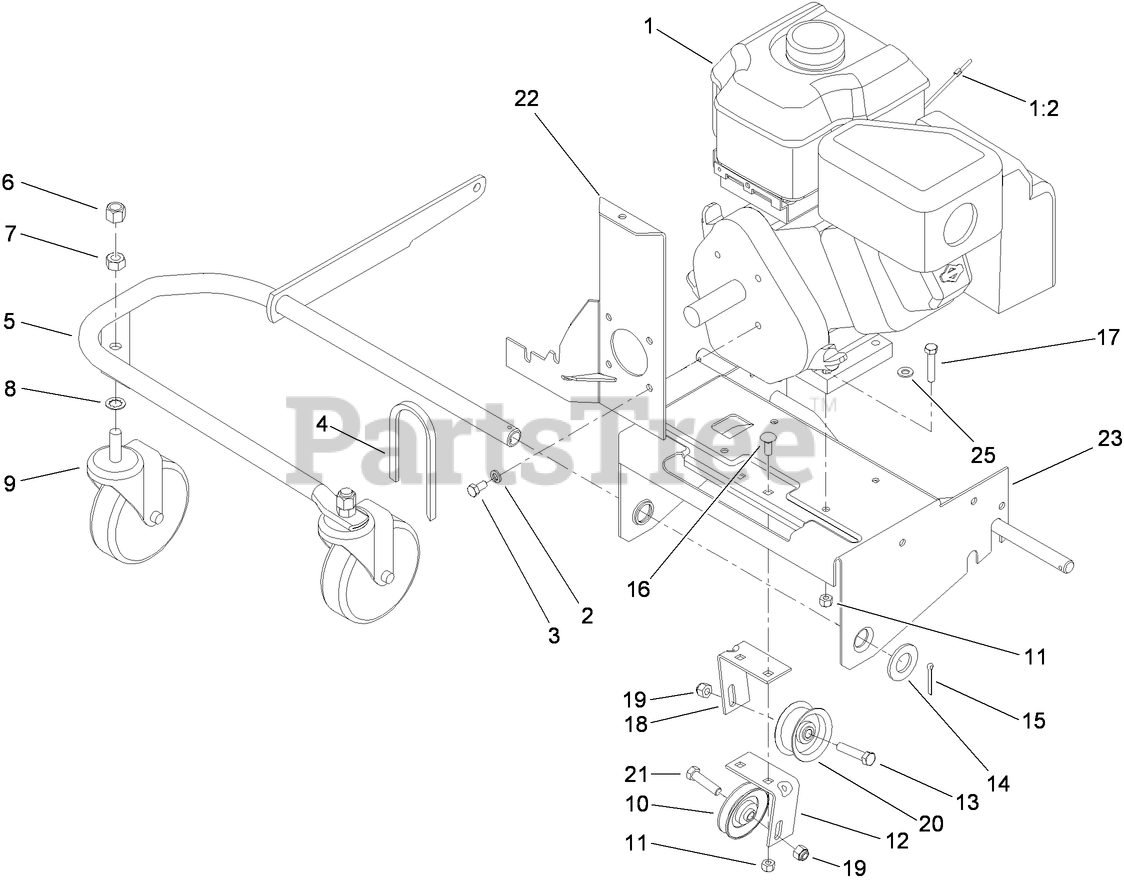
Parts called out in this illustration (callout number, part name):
1:2	STOP-ROPE
2	WASHER-LOCK
3	SCREW-HH
4	BELT-V
5	FRONT WHEEL SUPPORT ASM
6	NUT-LOCK, NI
7	NUT-HH
8	WASHER-LOCK/INT
9	CASTER
10	PULLEY-IDLER
11	NUT-LOCK, NI
12	BRACKET-IDLER MOUNT, LH
13	SCREW-HH
14	WASHER-FLAT
15	PIN-COTTER
16	BOLT-CARR
17	SCREW-HH
18	BRACKET-IDLER MOUNT, RH
19	NUT-LOCK, NI
20	PULLEY-IDLER
21	SCREW-HH
22	STABALIZER BRACKET ASM
23	PLATE-ENGINE
25	WASHER-PLAIN
